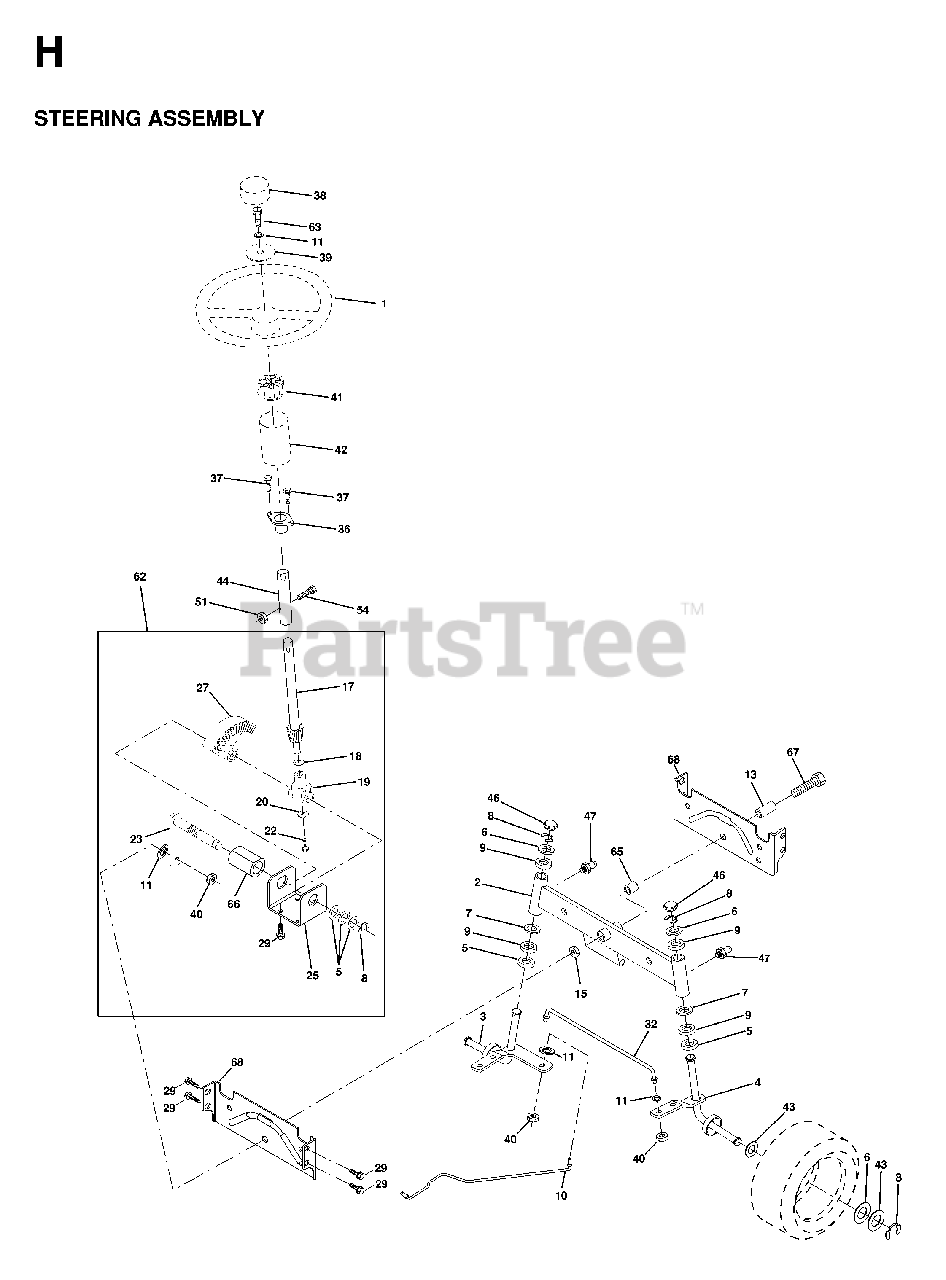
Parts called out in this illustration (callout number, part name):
2	FRONT AXLE ASSY
3	SPINDLE ASM LH
4	SPINDLE ASM RH
8	RING CLIP
9	BRNG T
10	LINK.DRAG.DROPPED.LT
11	WASHER, LOCK 3/8
13	BEARING AXLE
15	NUT-LOC,FLANGE LT
17	SHAFT ASM STEERING
18	THRUST WASHER
19	SHAFT,SUPPORT
20	WASHER
22	SCREW HEX SOCKET 1/4-20 X 5/8
23	SHAFT PITMAN
25	BRACKET STEERING
27	GEAR.SECTOR
29	SCREW
32	ROD ASSY/TIE BALL
36	BUSHING, STEERING
38	RP INSERT
39	WASHER T
40	GRIPCO NUT
41	ADAPTER LT
42	STEERING BOOT, GRAY
44	EXT SHAFT STEERING
46	CAP.SPINDLE
47	ZERK M
51	NUT.71038.31-18.HEX.NYLOCK
54	BOLT.5/16-18X1-1/4 FULL.THREAD
62	KIT, STEERING ASSEMBLY
65	SPACER AXLE
66	BEARING ARM
67	BOLT.HEX.FINISHED.5/8
68	AXLE, BRACE
